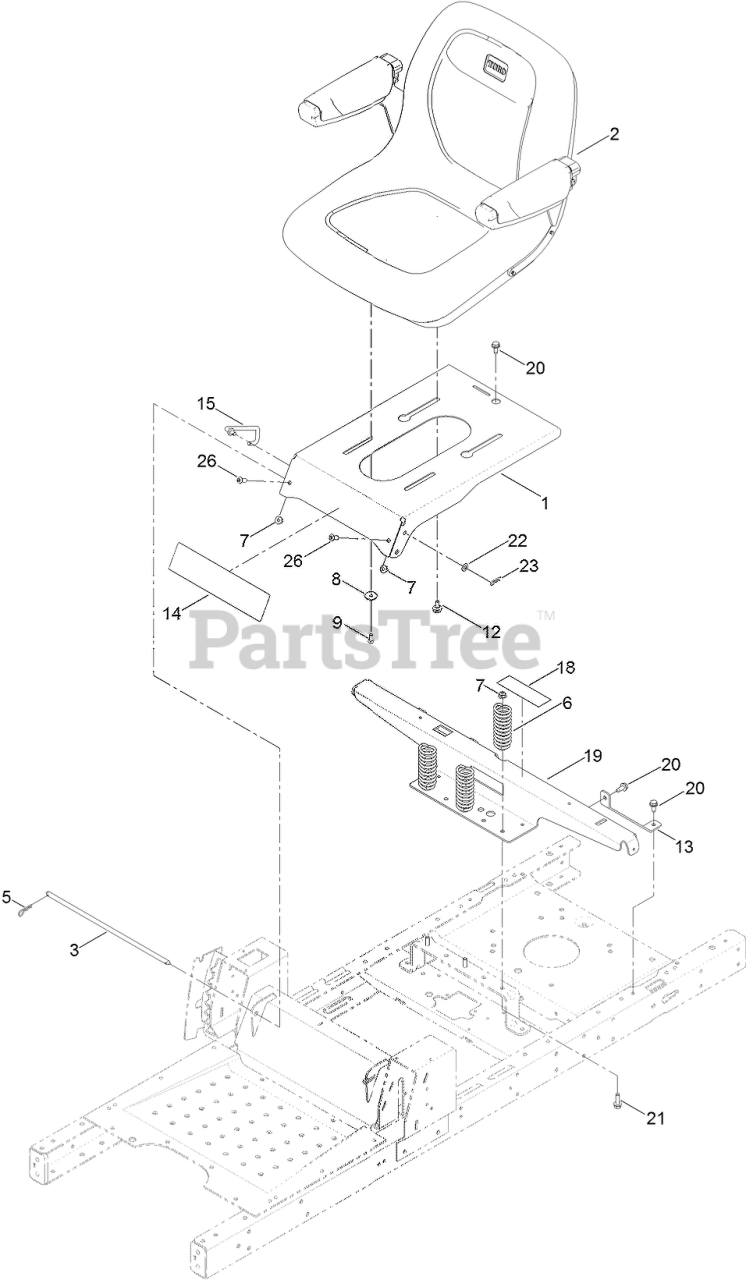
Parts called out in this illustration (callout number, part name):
1	PAN-SEAT
2	SEAT-18 Inch
3	ROD-PIVOT, NARROW
5	PIN-COTTER
6	SPRING-COMPRESSION
7	NUT-HF, NI
8	WASHER-PIVOT
9	SCREW-HH
12	BOLT-SHOULDER
13	SUPPORT-TANK, REAR
14	DECAL-TIMECUTTER
15	STOP-SEAT
18	DECAL-SERVICE, CE
19	SUPPORT-POD
20	SCREW-HWHTF
21	SCREW-HHF
22	WASHER-PLAIN
23	PIN-COTTER
26	SCREW-HSBH
